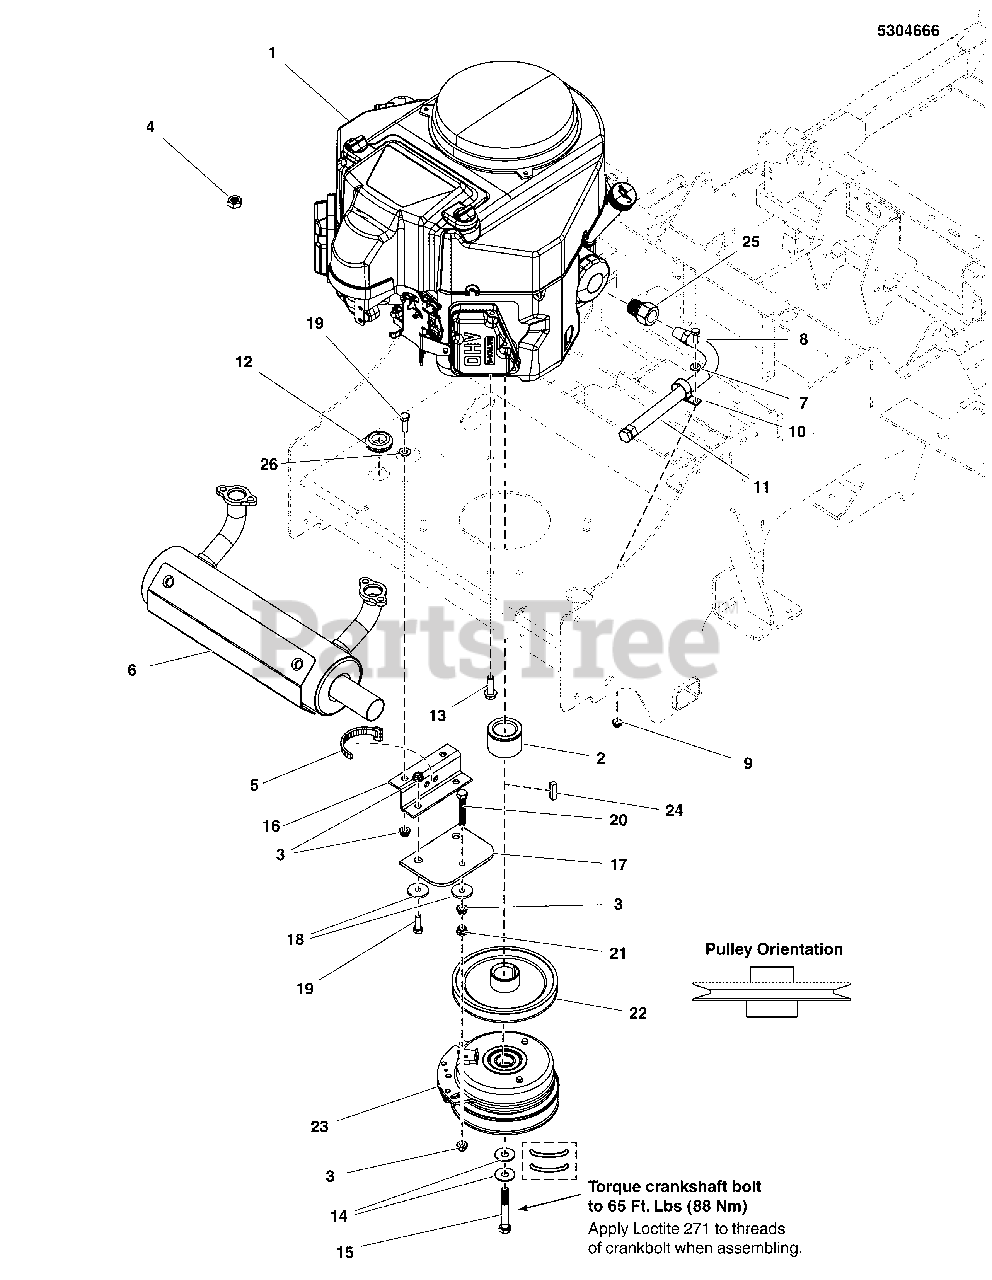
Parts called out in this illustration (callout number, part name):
1	ENGINE, 24HP, KAWI, FR730V, 1-1/8 CRANK
2	SPACER, Crankshaft
2	SPACER, 1.13 X 1.75 X 1.03, CZ
3	NUT, Flange Nylock, 5/16-18
4	NUT, 3/8-24 HEX JAM (SV)
5	TIE, 6" Self-Locking
6	MUFFLER, KAWI, HORIZONTAL, 5" CAN
7	WASHER, Flat, 1/4
8	CAPSCREW, Hex Head, 1/4-20 x 3/4 (stiffener to top of cover)
9	NUT, Flange Nylock , 1/4-20
10	CLAMP, VINYL INSULATED, 1.00
11	HOSE, OIL DRAIN
12	GROMMET, 7/8"
13	BOLT,Hex Flange, 3/8-16 X 1-1/4, GR5
14	BELLEVILLE, WASHER, 1.1875 X .442 X .089
15	BOLT, Crankshaft
15	BOLT, CRANKSHAFT,7/16-20X2-3/4, GD8
16	ANCHOR, CLUTCH, IS600-IS700 - BLK
17	PAD, Clutch Anchor
18	WASHER, CLUTCH ANCHOR, 5/16
19	CAPSCREW, Hex Head, 5/16-18 x 1 1/4
20	BOLT, 5/16-18 X 2-1/4
21	NUT, Hex Serrated Flange, 5/16-18,
22	PULLEY, PUMP DRIVE, 4.857 OB X 1-1/8
23	CLUTCH, WARNER, 125 FT LBS, 1-1/8" BORE
24	KEY 1/4 SQ X 1 1/2 LONG
25	ADAPTER, Oil Drain
26	WASHER, Flat, 5/16
